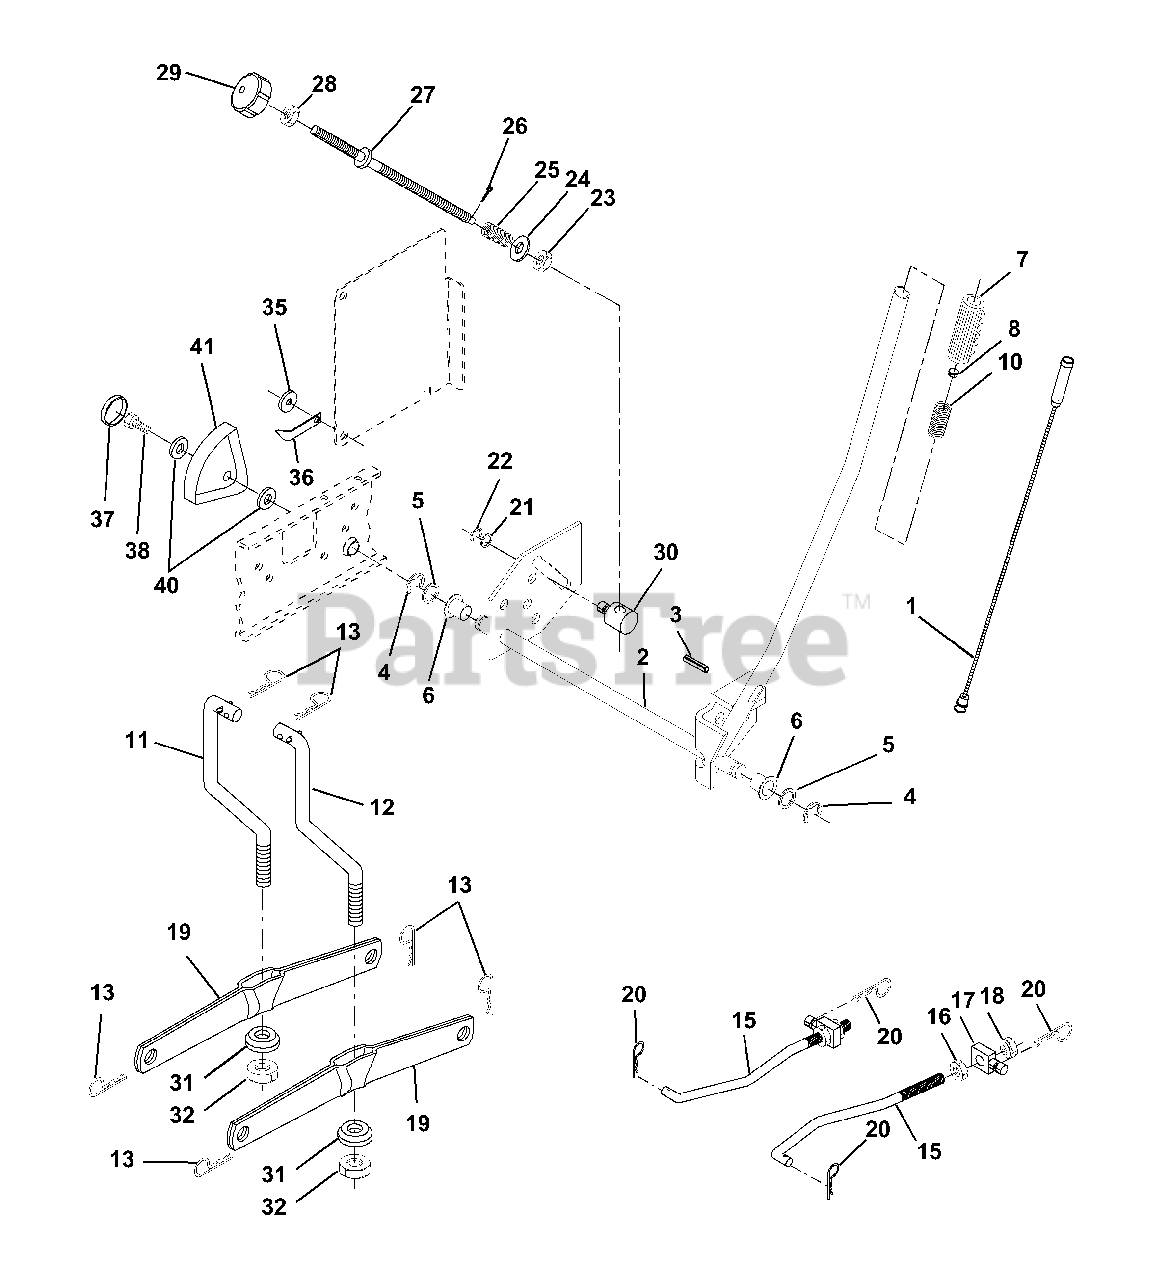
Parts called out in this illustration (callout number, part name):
1	Wire Asm Inner W/plunger 20 56
2	Shaft Asm Lift RH w/Inf
3	Pin Groove 1 500 Zinc
4	E Ring #5133-62
5	Washer 21/32 X 1 X 21 Ga
6	Bearing Nylon Blk 629 Id
7	Grip Handle Fluted Blk
8	Button Plunger Black
10	Spring Cprsn 3 750 Oiled
11	Link Lift LH
12	Link Lift RH
13	Retainer Spring
15	Link Front
16	Nut Jam Hex 1/2-13 Unc
17	Trunnion Blk Zinc
18	Nut Lock W/wsh 1/2-13unc
19	Arm Suspension Rear
20	Retainer Spring
21	Washer 15/32 X 3/4 X 16 Ga
22	Ring Klip #t5304-37
23	Nut Special
24	Washer 13/32 X 5/8 X 16 Ga
25	Spring Compression Inf. Hgt.
26	Pin Cotter 3/32 X 1/2
27	Rod Adj Lift Zinc 9 00 Wrk Lg
28	Nut Hex Jam 3/8-16 Unc
29	Knob Inf 3/8-16 Unc Blk W/sym
30	Trunnion Dp Stop Dbl Thds PLT
31	Bearing Pvt Lift Spherical
32	Nut Crownlock 3/8-24
35	Washer Nylon .44 x .75 x .032
36	Pointer Height Indicator
37	Plug Hole Blk 1.485/1.515
38	Screw Thdrol 5/16-18 x 3/4 TYT
40	Washer 11/32 x 1-1/2 x 10 Ga.
41	Scale Ind. Height Blk
